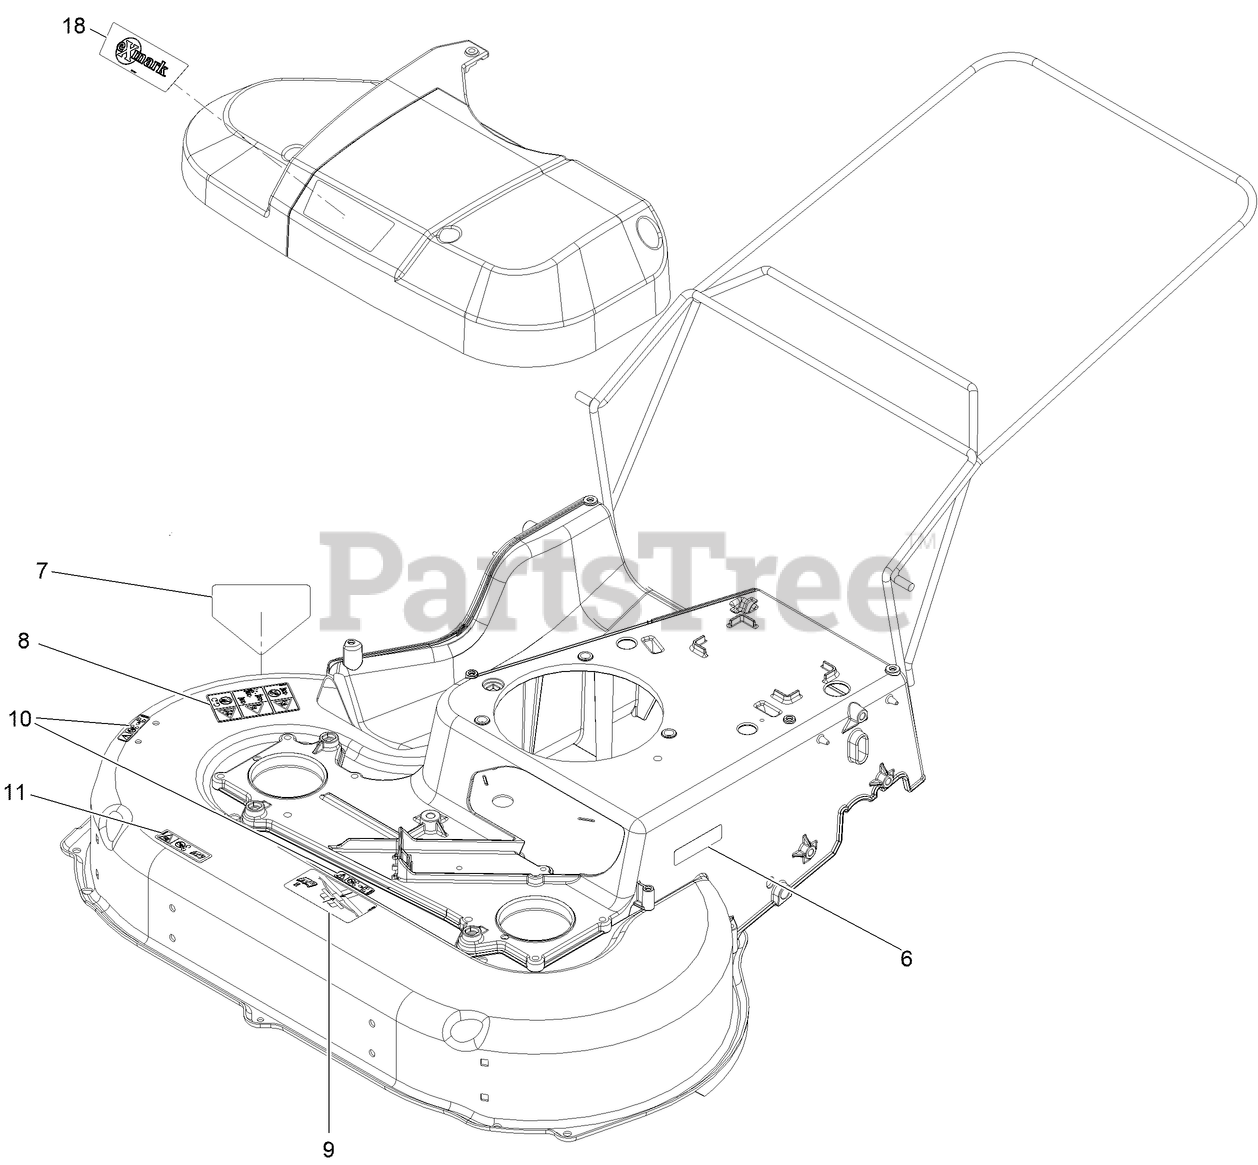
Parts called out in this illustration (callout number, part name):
6	DECAL-ARRESTOR, SPARK
7	DECAL-DANGER
8	DECAL-DANGER, CE
10	DECAL-WARNING
11	DECAL-WARNING
18	Decal-Exmark, 30
